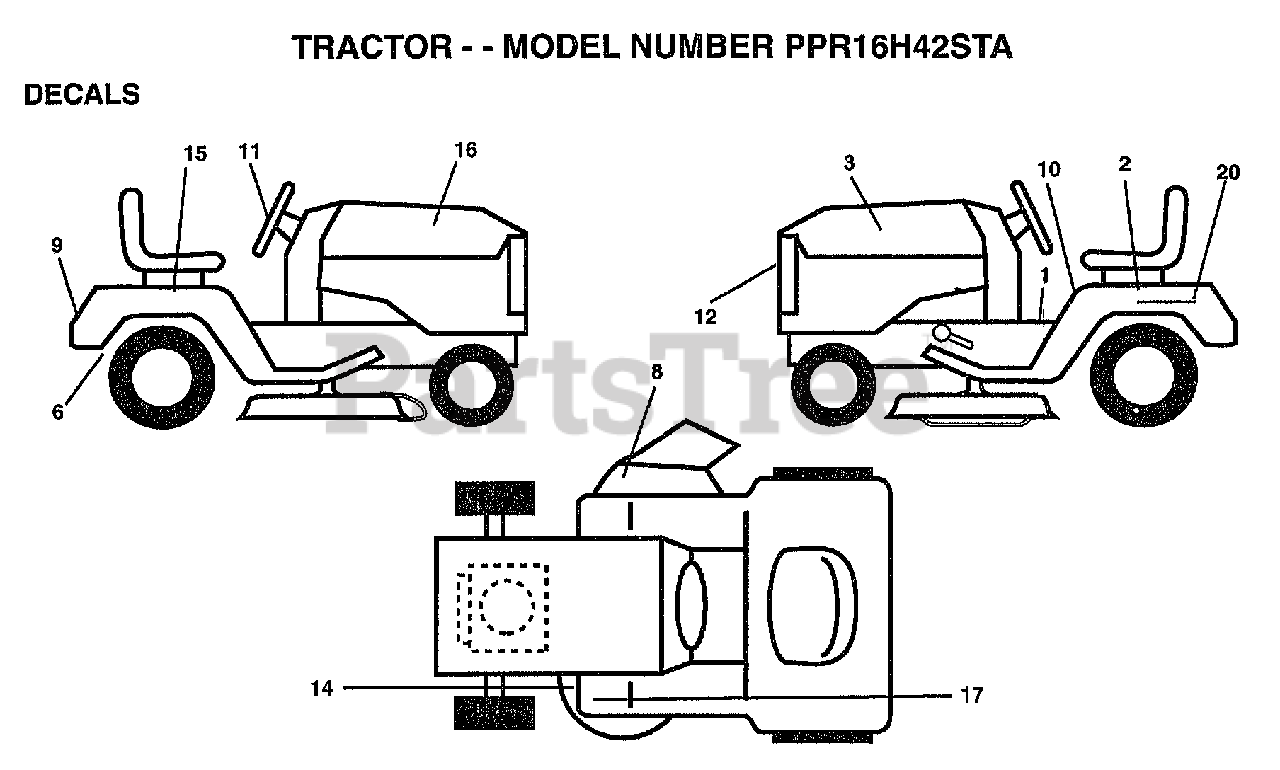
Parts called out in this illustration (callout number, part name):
1	DECAL SADDLE OPER
2	DECAL.FENDER.SD.AUTO
3	DECAL.HOOD.LH
6	DECAL DRAWBAR LH
8	"DECAL, WARNING"
9	DECAL.FENDER.LOGO
10	DECAL.CAUT.ENG/FR
11	DECAL.INS.WHL.STRG
12	DECAL.GRILLE.
14	"DECAL-SCHEM,BELT"
15	DECAL.FENDER.SD.RH.
16	DECAL.HOOD.RH
17	DECAL T
20	DECAL.BATRY.3-3908
